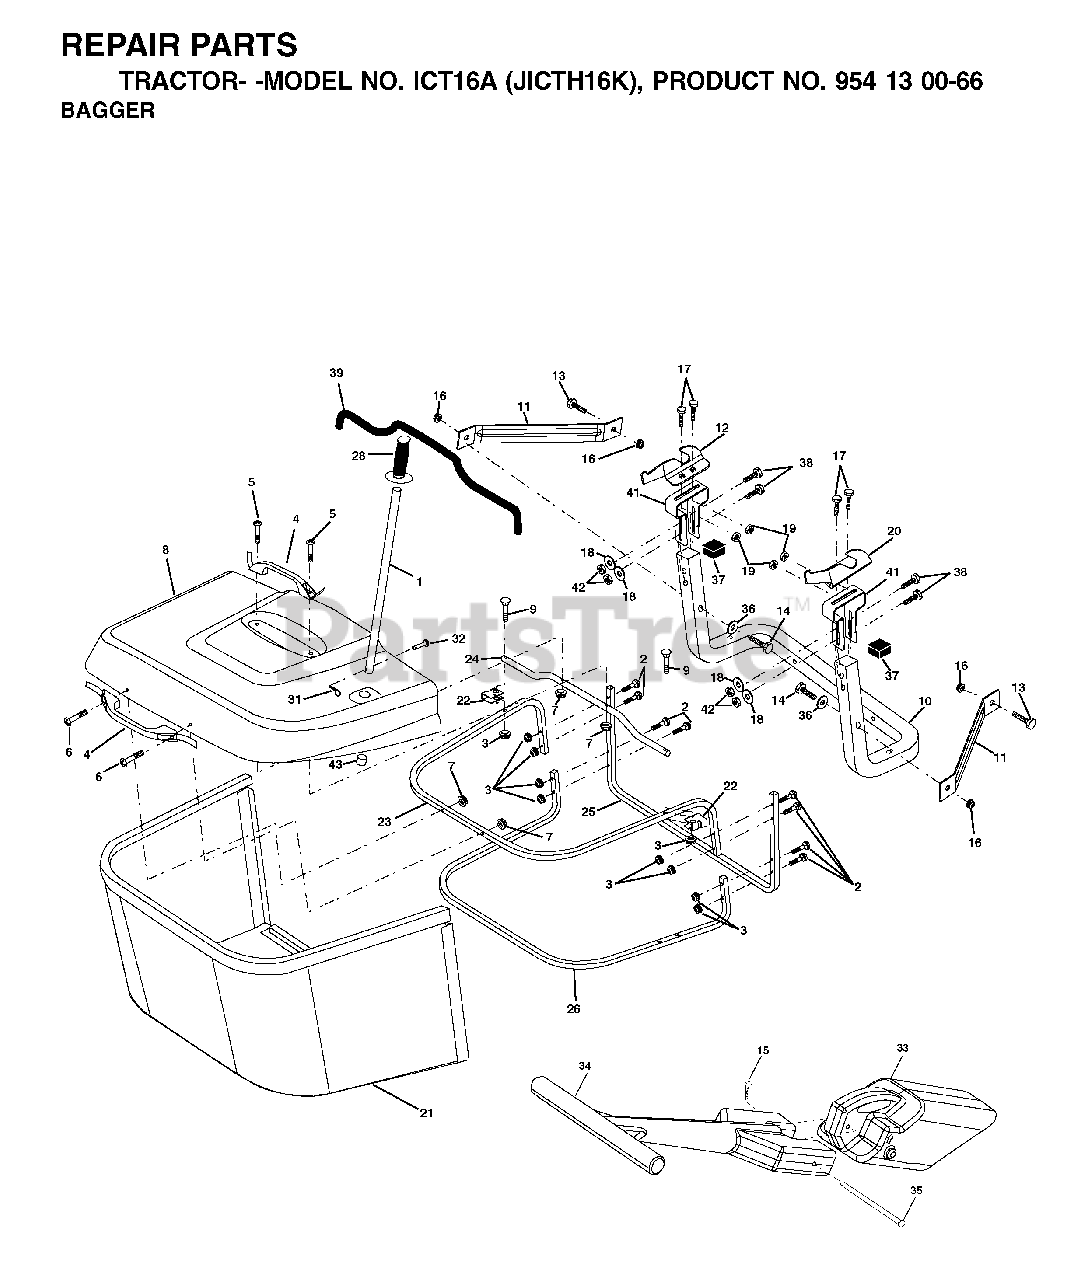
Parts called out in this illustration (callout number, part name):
1	TUBE HANDLE
3	NUT T
5	SCREW.PAN.HEAD
11	BRACKET
14	BOLT-HEX EAK
15	RETAINER-SPRNG RB
16	NUT LOCK FLG 3/8-16 UNC
17	BOLT
18	WASHER M
19	NUT LOCK HEX FLANGE 5/16-18
20	BRACKET
21	GRASS BAG
22	BRACKET
23	TUBE
24	TUBE
26	TUBE
28	GRIP.HANDLE.BLACK
31	RETAINER M
32	RIVET,DRILLED
33	PLUG
35	PIN
36	WASHER
38	BOLT.5/16-18X2.5
41	BRKT, BAGGER
42	NUT.71038.31-18.HEX.NYLOCK
43	PLUG, TUBING END
